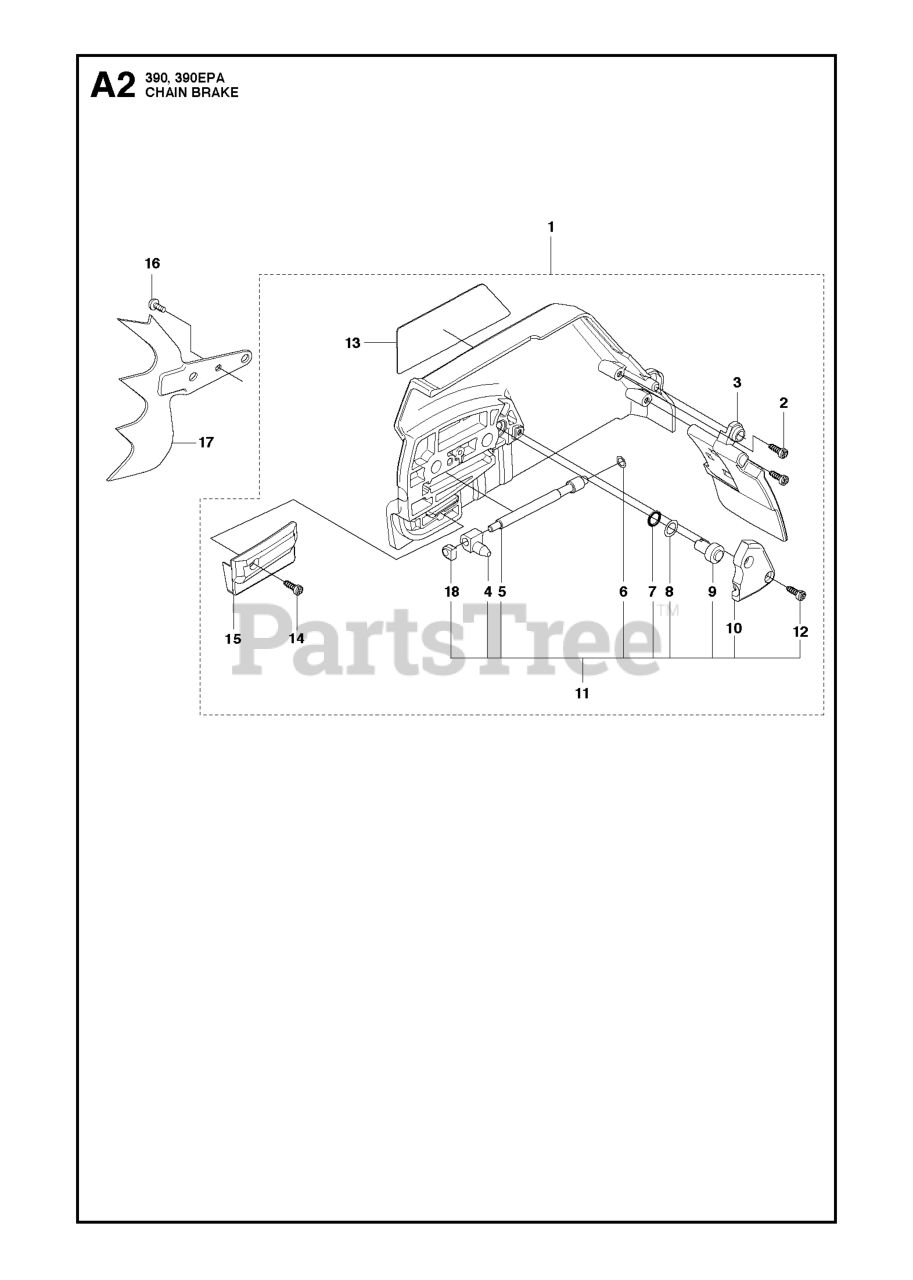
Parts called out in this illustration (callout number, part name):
1	CLUTCH COVER ASSY
5	WORM SCREW / ADJUSTER
9	WORM WHEEL
11	KIT-CHAIN TENSIONER
15	CHAIN GUIDE
17	FELLING DOG
